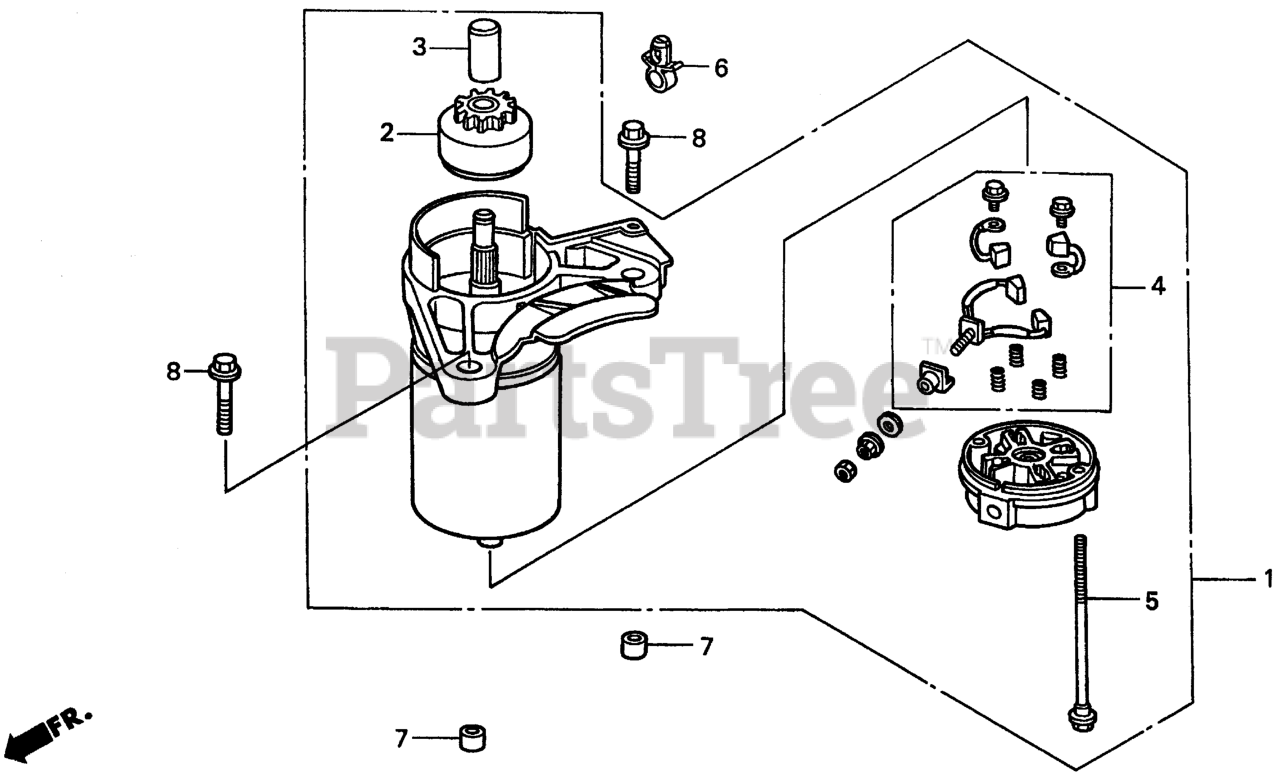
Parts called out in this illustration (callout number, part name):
1	MOTOR ASSY., STARTER
2	DRIVE ASSY.
3	STOPPER SET, PINION
4	BRUSH SET
5	BOLT, THROUGH
6	CLIP, WIRE HARNESS
7	PIN, DOWEL (10X12)
8	BOLT, FLANGE (8X35)
